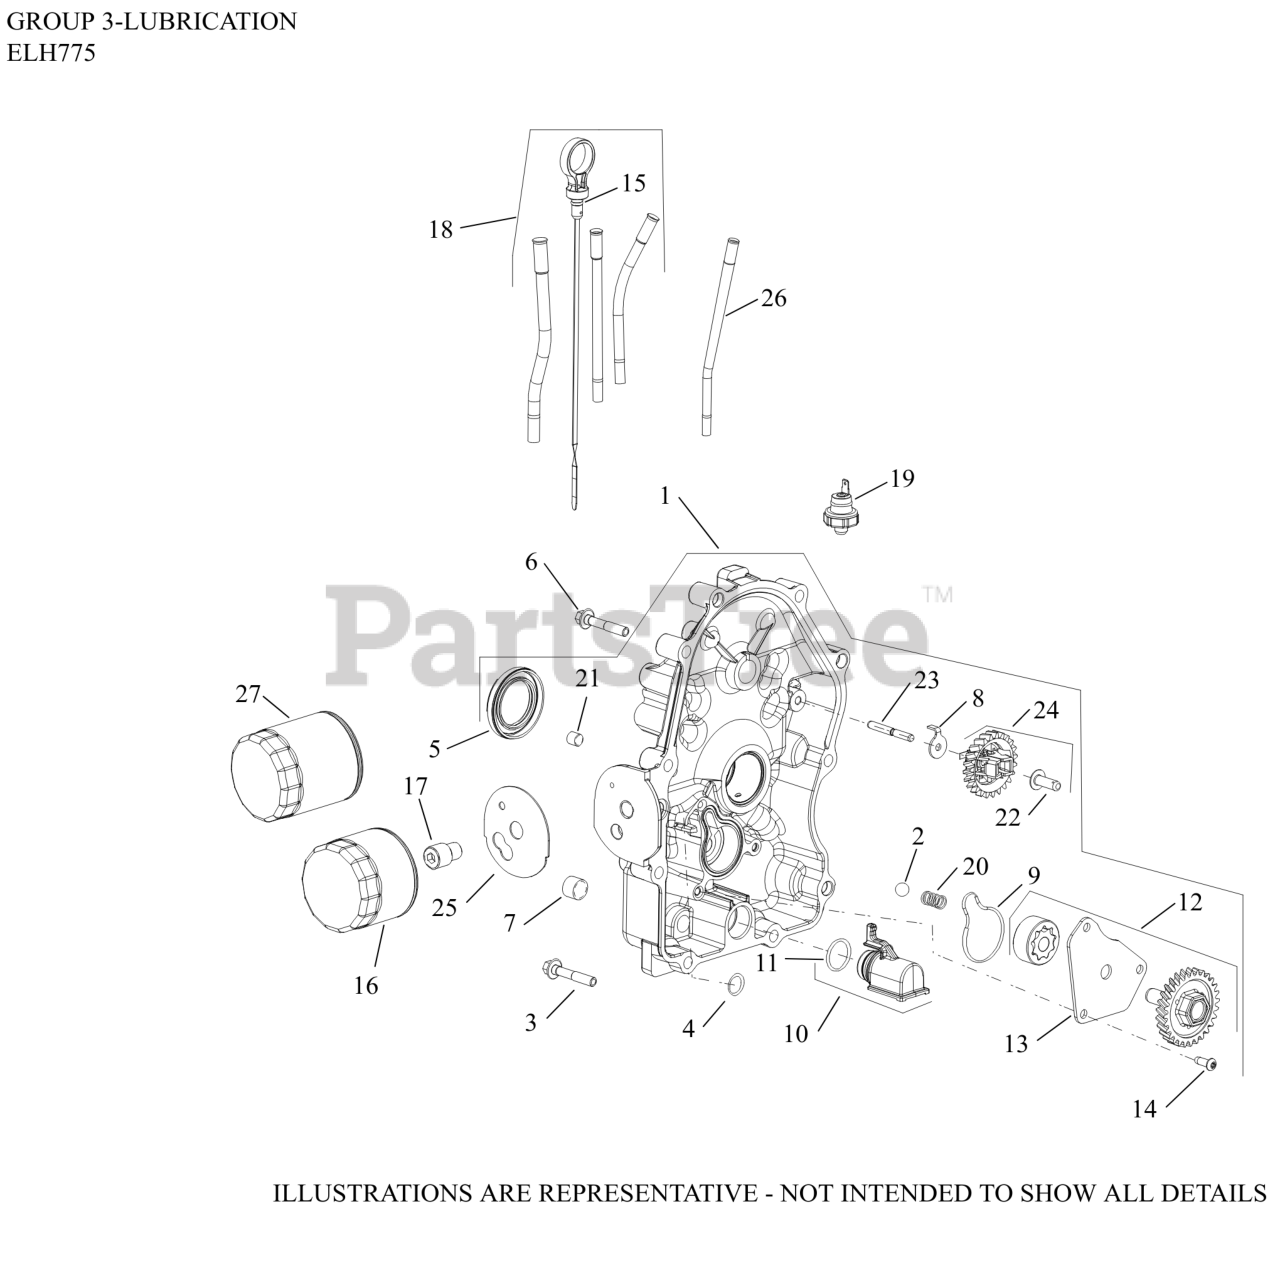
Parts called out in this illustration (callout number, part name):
1	CLOSURE PLATE ASSY
2	PRESSURE RELIEF BALL
3	SCREW, FLG M8X1.25X45
6	SCREW, HEX FLANGE
7	PLUG, PIPE CTSK 3/8"
8	TAB, LOCKING
9	SEAL, OIL PUMP COVER
10	PICK-UP ASSEMBLY, OIL
11	O-RING, OIL PICK-UP
12	PUMP ASSEMBLY, OIL
13	COVER, OIL PUMP
14	SCREW, BUTTON HEAD
16	OIL FILTER
16	NIPPLE, OIL FILTER
18	KIT, DIPSTICK/DIPSTICK TUBES
19	SENSOR, OIL PSI
20	SPRING, COMPRESSION
21	PLUG, CTSK PIPE 1/8"
22	PIN, GOVERNOR REGULATING
23	SHAFT, GOVERNOR GEAR
24	KIT, GOVERNOR GEAR W/PIN
